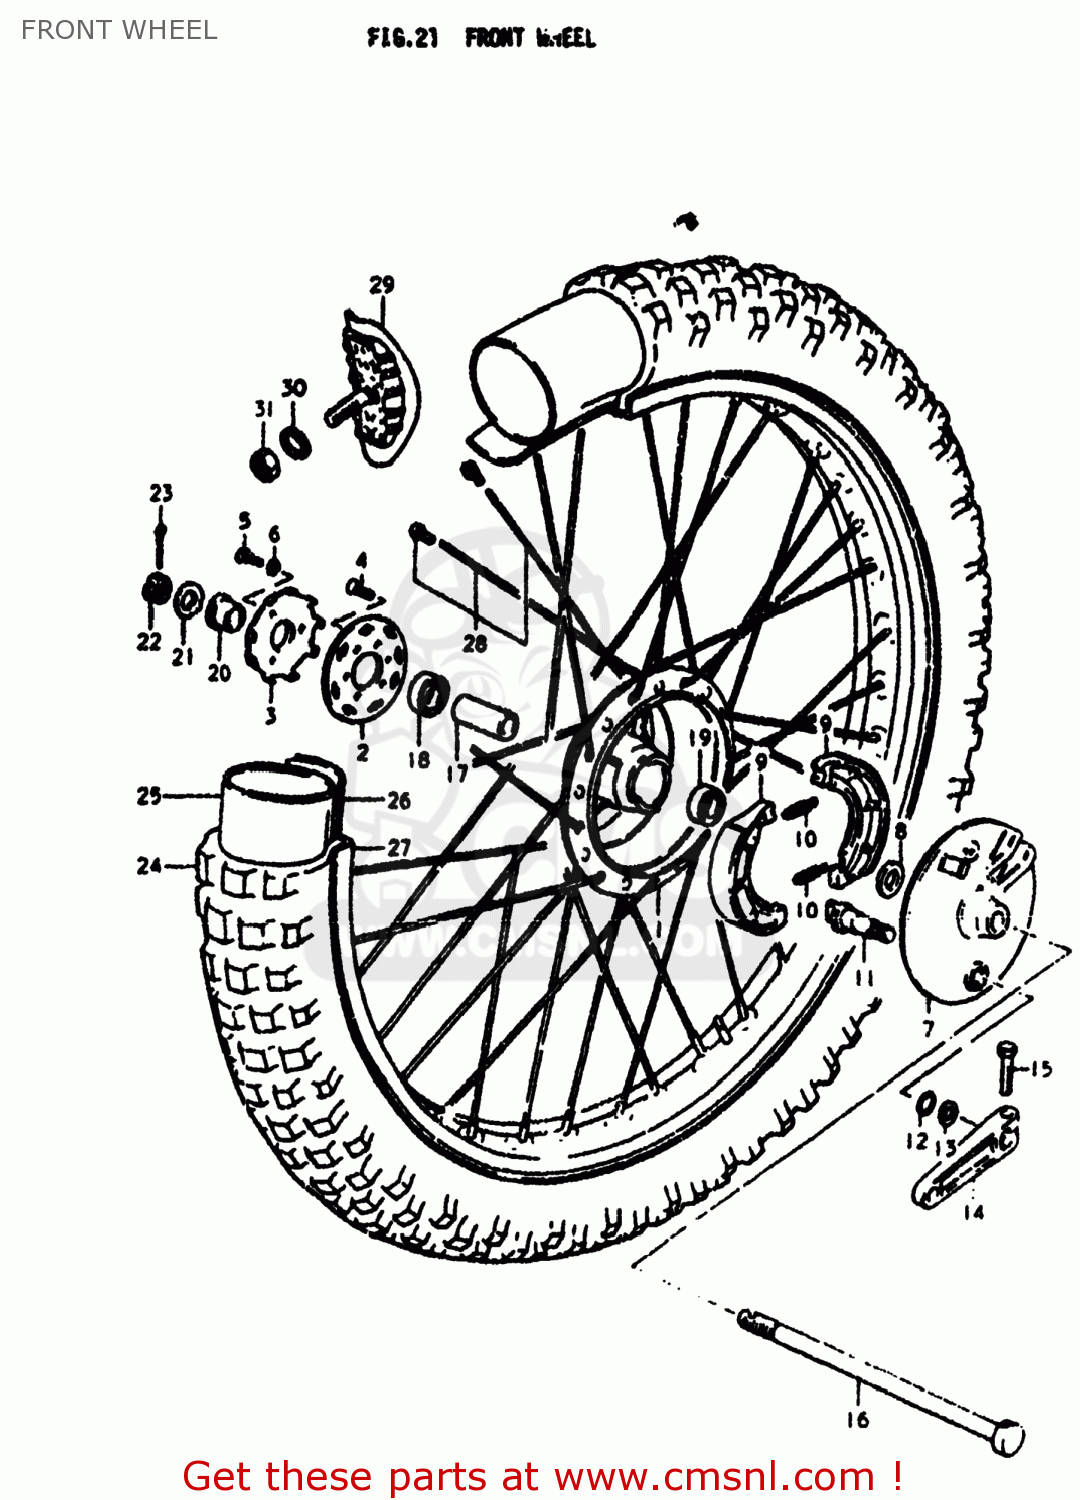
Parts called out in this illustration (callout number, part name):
1	HUB,FRONT
2	FLANGE,FRONT HUB,RIGHT
3	RETAINER,FR HUB BEARING,R
4	SCREW
5	BOLT, UPPER
6	LOCK WASHER
7	PANEL,FRONT HUB
8	BOSS
9	SHOE,BRAKE
10	SPRING(L:34)
11	CAM,FRONT BRAKE
12	O RING(D:2.5,ID:11.4)
13	WASHER(12.5X20X1)
14	LEVER,FRONT BRAKE CAM
15	BOLT
16	AXLE,REAR
17	SPACER (12.6X19X52)
18	BEARING
19	BEARING, LH
20	SPACER,FR AXLE,R
21	WASHER
22	NUT, REAR AXLE
23	COTTER PIN
24	TIRE,FRONT
25	TUBE
26	PROTECTOR,WHEEL,INNER
27	RIM,FRONT WHEEL
28	SPOKE SET,FRONT
29	STOPPER,BEAD
30	WASHER
31	NUT
